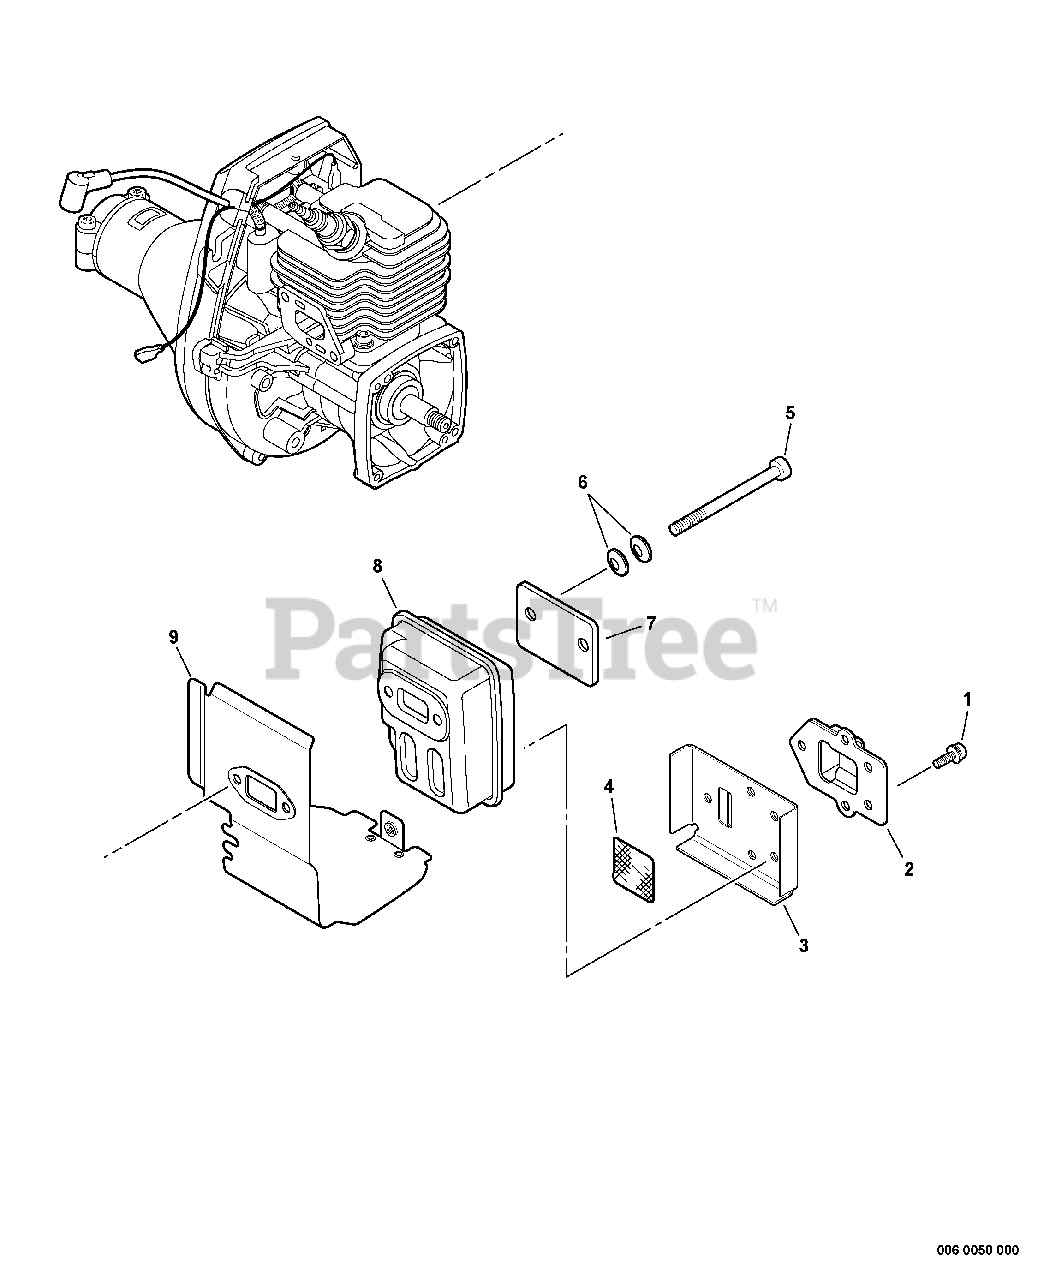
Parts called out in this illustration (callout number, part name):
1	SCREW 4×12
2	GUIDE, EXHAUST
3	GASKET, EXHAUST
4	SCREEN, SPARK ARRESTER
5	BOLT 5×55
6	CONICAL WASHER
7	PLATE, EYE
8	MUFFLER
9	HEAT SHIELD, EXHAUST
